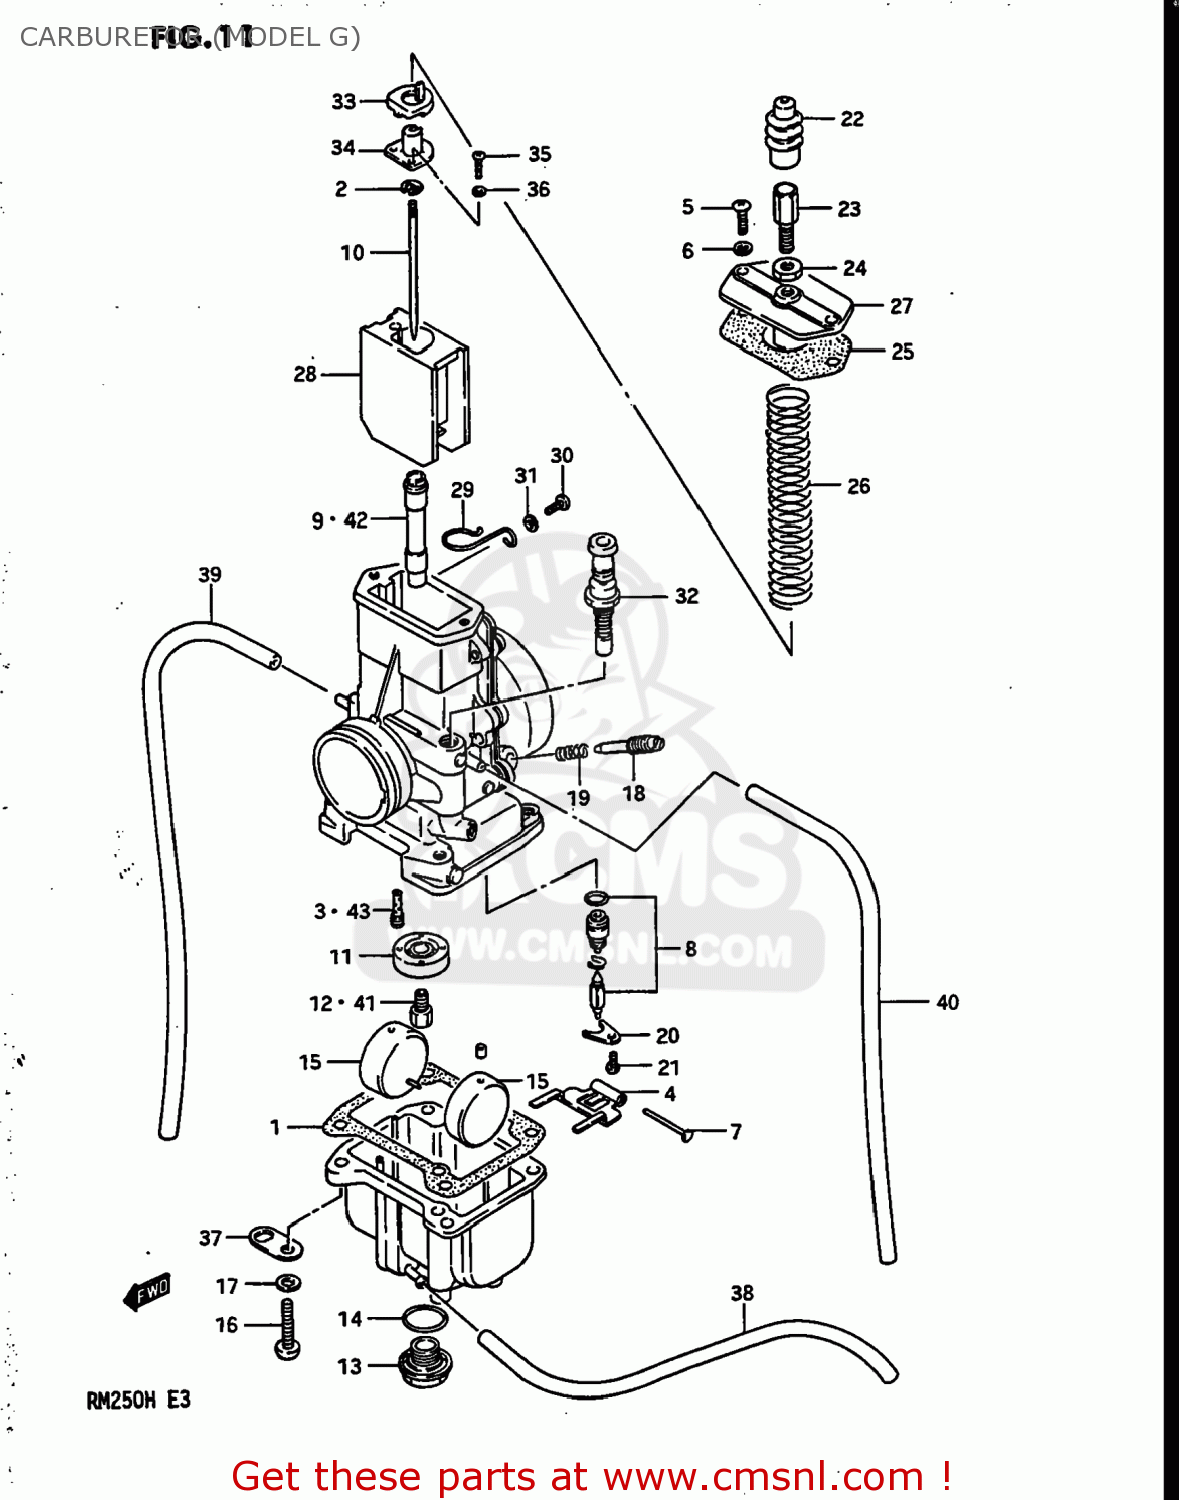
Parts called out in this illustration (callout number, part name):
1	GASKET,FLOAT CAHMBER (NAS)
2	CLIP
3	JET,PILOT(50)
4	ARM,FLOAT
5	SCREW
6	LOCK WASHER
7	PIN,FLOAT
8	VALVE ASSEMBLY,NEEDLE
9	JET,NEEDLE(R-0)
10	NEEDLE JET
11	RING,MAIN JET FIXING
12	JET,MAIN(300)
13	SCREW,GUIDE
14	O RING,DRAIN PLUG
15	FLOAT
16	SCREW
17	LOCK WASHER
18	SCREW,PILOT AIR
19	SPRING
20	PLATE
21	SCREW
22	CAP,CABLE ADJUSTER
23	ADJUSTER,CABLE
24	NUT
25	GASKET,MIXING CHAMBER (NAS)
26	SPRING,THROTTLE VALVE
27	CAP,CARBURETOR,TOP
28	VALVE,THROTTLE,CA (3.0)
29	CLIP
30	SCREW
31	LOCK WASHER
32	PLUNGER ASSEMBLY
33	SEAT,RETURN SPRING
34	PLATE,NEEDLE JET
35	SCREW
36	LOCK WASHER
37	PLATE
38	HOSE
39	HOSE
40	HOSE
41	JET
42	JET,NEEDLE
43	JET,PILOT
